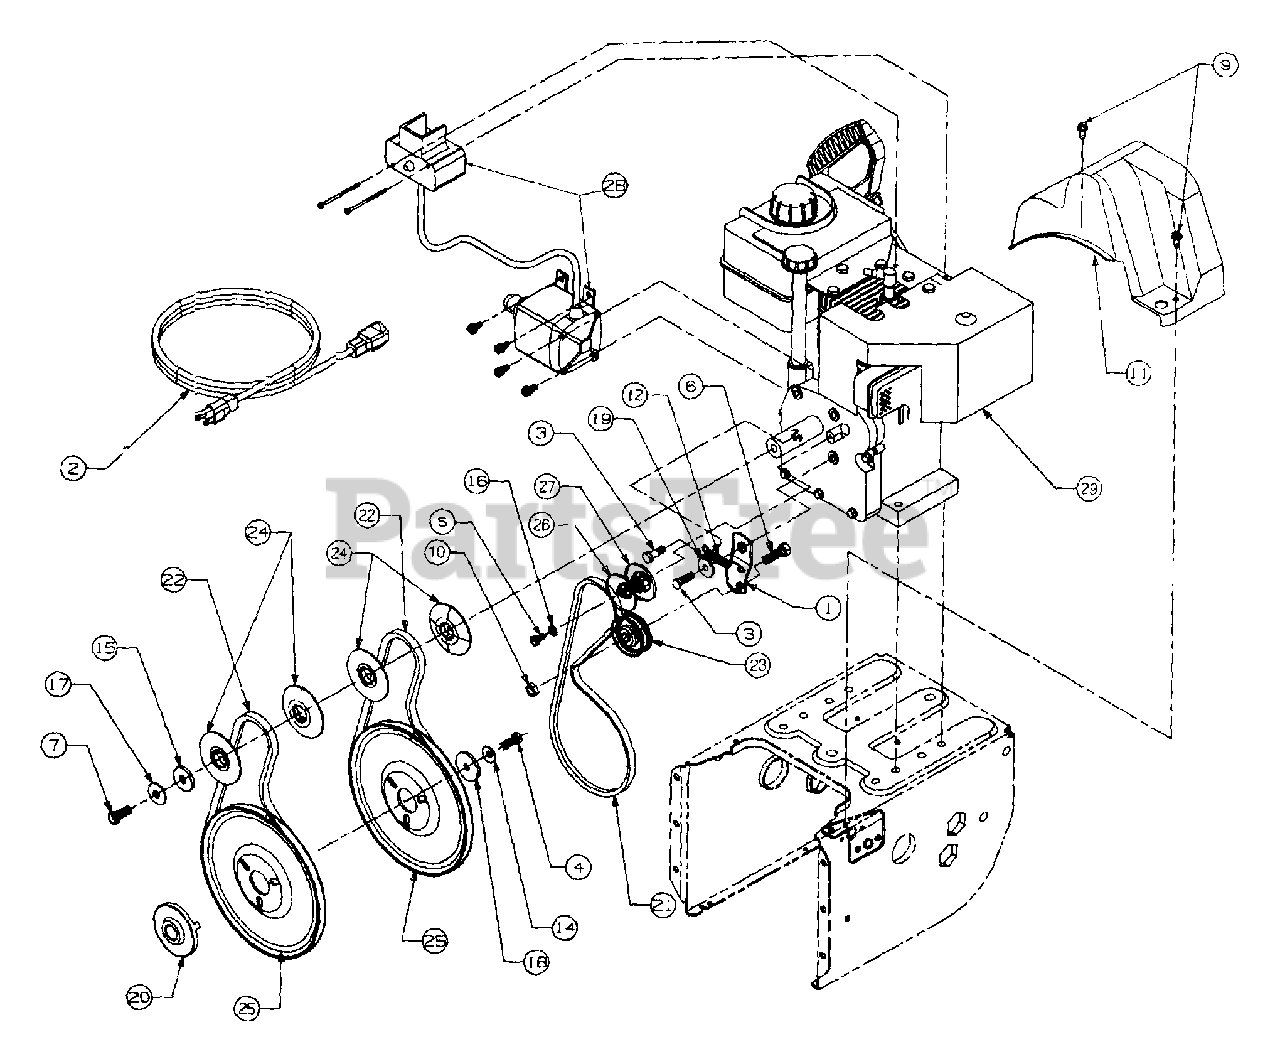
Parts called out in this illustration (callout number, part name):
3	Screw
4	Screw
5	Screw
6	Screw
7	Screw
9	Screw
10	Nut, Hex
11	Belt Cover
12	Spring
14	Washer - Bell
15	Washer - Flat
16	Washer - Lock
17	Washer - Bell
18	Washer - Flat
19	Shoulder Spacer
20	Pulley, Adapter
21	V-Belt
22	V-Belt Matched
23	Idler, Flat
24	Pulley, Half
25	Pulley - Auger
26	Pulley Half
27	Pulley Half
28	Starter
29	Engine
